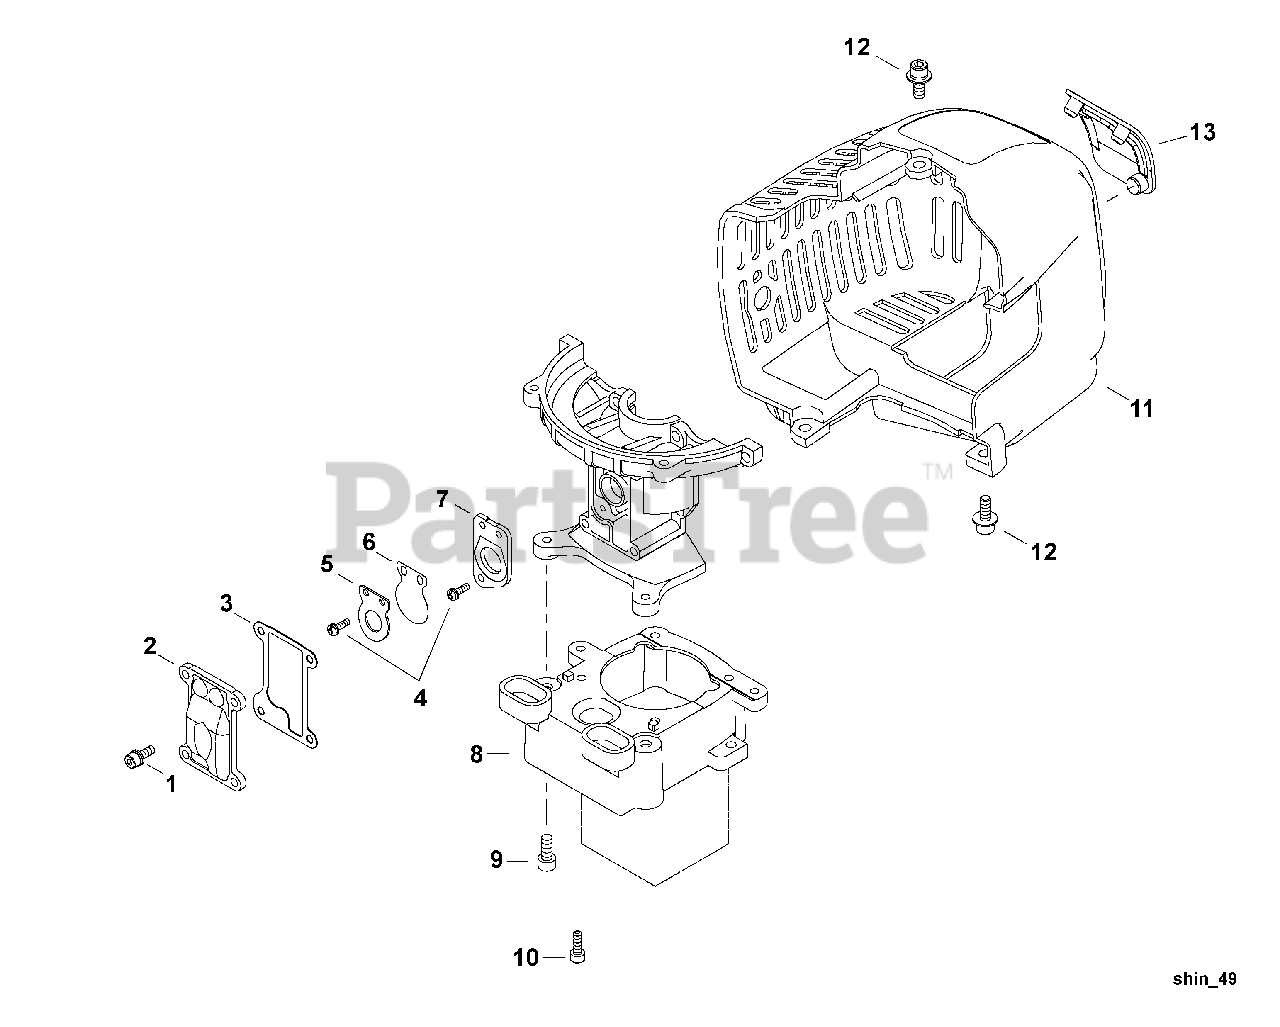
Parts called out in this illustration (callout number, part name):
1	BOLT M4×12
2	COVER, REED VALVE
3	GASKET, REED VALVE
4	SCREW M3×10
5	STOP, REED VALVE
6	VALVE, REED
7	PLATE, REED BACKING
8	ADAPTOR, GEAR CASE
9	BOLT 5×12
10	BOLT 4×12
11	COVER, ENGINE
12	BOLT, ADHESIVE M5×14
13	COVER, SPARK PLUG
